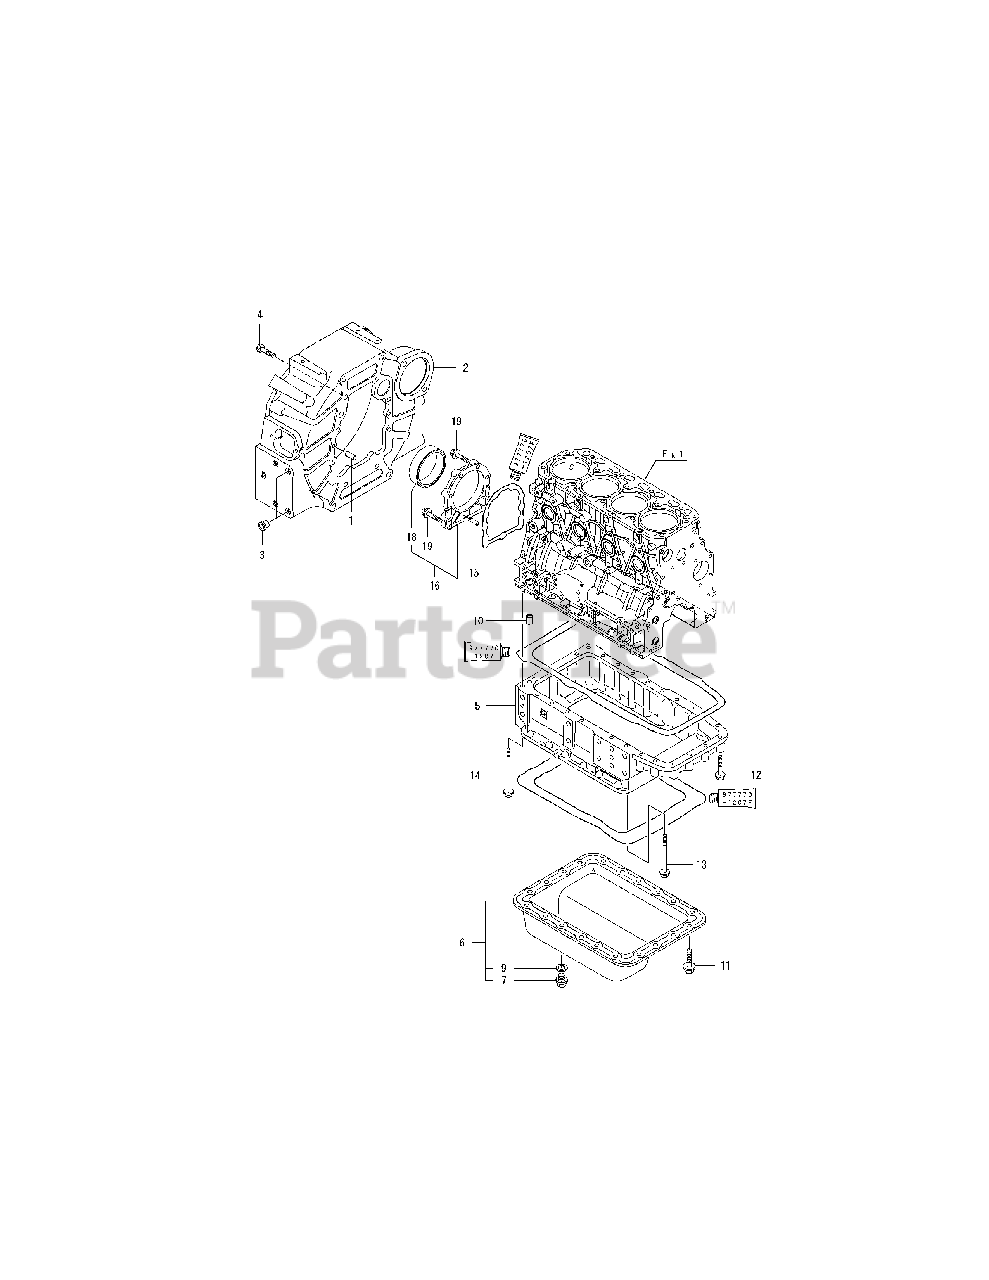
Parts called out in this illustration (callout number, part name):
2	HOUSING, FLYWHEEL
6	COVER ASSY, OIL SUMP
11	BOLT M 8X 12 PLATED
12	BOLT M 8X 50 PLATED
13	BOLT M 8X100 PLATED
14	BOLT M 8X120 PLATED
16	CASE ASSY, OIL SEAL
